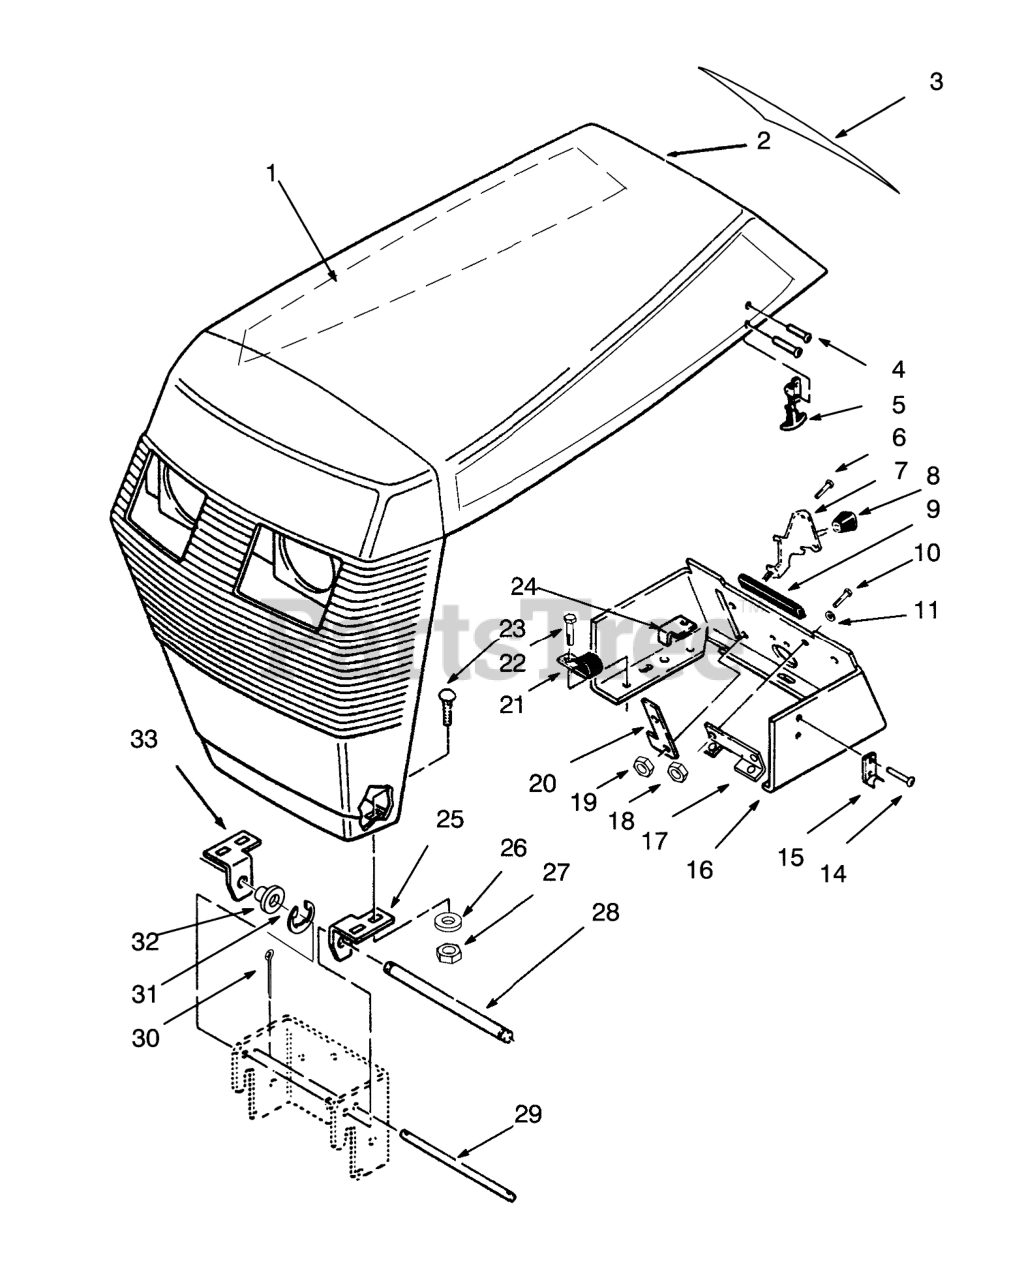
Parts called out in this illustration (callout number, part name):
1	DECAL-HOOD 416-H R H
2	Hood (Incl. Ref. #3)
3	Decal-Danger
4	RIVET-POP
5	Handle Assemblly (Incl. Ref. #15)
6	SCRW-PHC
7	CONTROL-THROTTLE
8	KNOB-CONTROL
9	EDGING-CONSOLE
10	SCREW-PAN
11	Washer-Lock
14	POPRIVET 1/8X 1/8 BK
15	KEEPER-LATCH
16	CONSOLE B
17	BRACKET
18	Nut
19	Nut
20	Washer
21	J-CLIP
22	Bolt
23	SCREW-CARR
24	STOP-PTO
25	BRACKET-GRILL, LH
26	WASHER-FLAT
27	NUT-LOCK, NI
28	ROD-GRILL PIVOT
29	ROD-HOOD STOP
30	Pin-Cotter
31	RING-RETAINING
32	BUSHING-NYLINER
33	BRACKET-GRILL, R H
